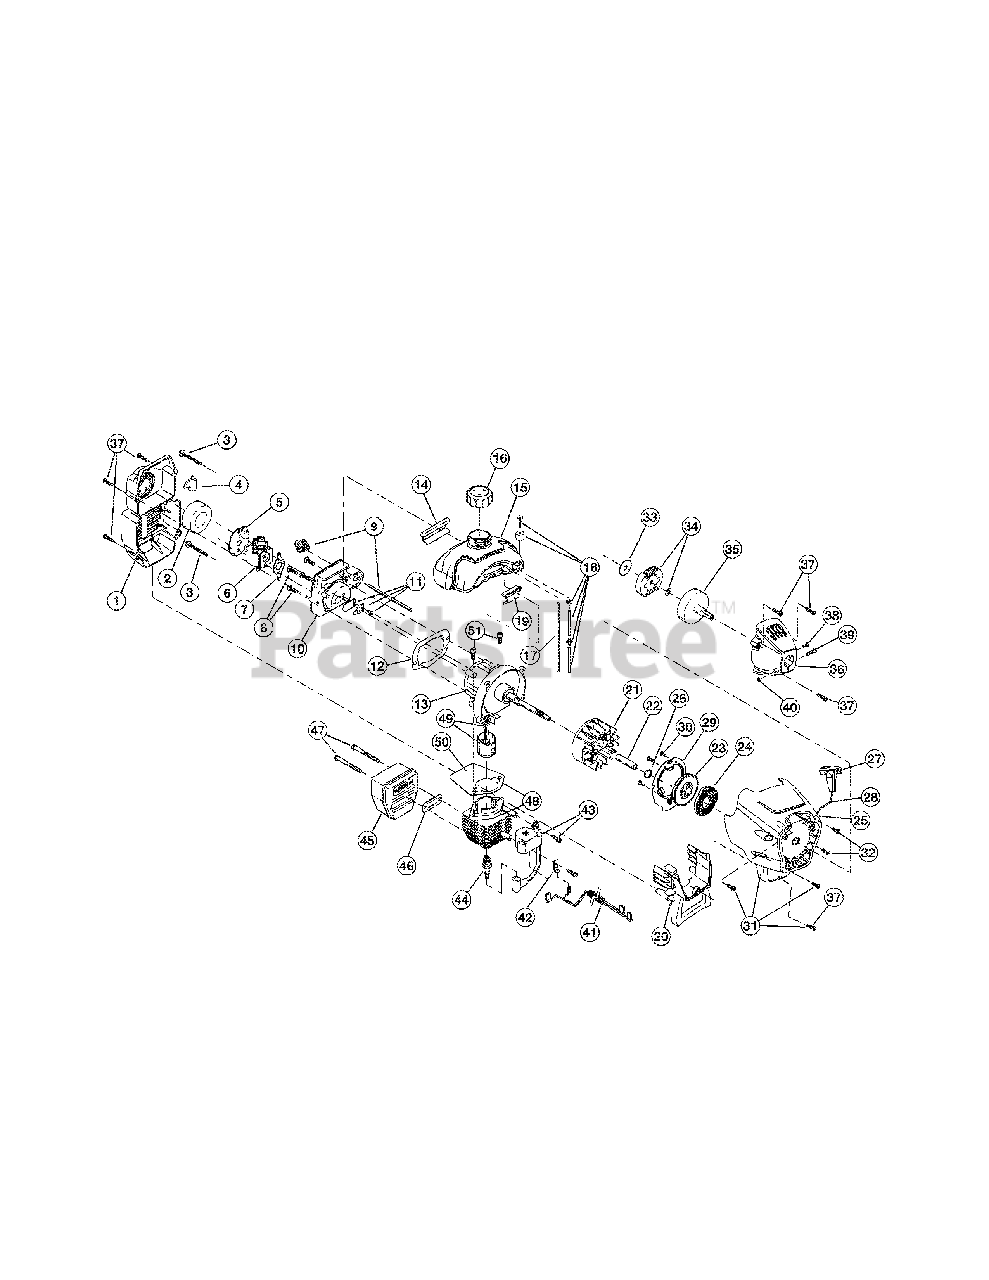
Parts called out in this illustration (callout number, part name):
1	Air Cleaner Assembly (includes 2 & 37)
2	Air Cleaner Filter
3	Carburetor Mounting Screw Assembly
4	Choke Extension
5	Choke Plate
6	Carburetor Assembly (includes 7 & 18)
7	Carburetor Gasket
8	Carb Mount Screw
9	Primer and Hose Assembly
10	Carb Mount Assembly (includes 8, 11 & 12)
11	Reed Assembly
12	Carburetor Mount Gasket
13	Crank Case Service Assembly (includes 8)
14	Rear Mounting Pad
15	Fuel Tank Assembly (includes 16-18)
16	Fuel Cap Assembly
17	Fuel Return Line
18	Fuel Line Assembly
19	Front Mounting Pad
20	Shroud Extension & Stand (includes 37)
21	Flywheel Assembly
23	Recoil Pulley Assembly (includes 26)
24	Recoil Spring
25	Rope Guide
26	Palnut
27	Pull Handle
29	Pressure Plate Assembly (includes 30)
30	Plate Screw
31	Starter Housing Assembly (includes 23-30, 32 & 37)
32	Housing Screw
33	Clutch Washer
34	Clutch Rotor Assembly
35	Clutch Drum Assembly
36	Clutch Cover Assembly (includes 37-40)
37	Cover Screw
38	Anti-Rotation Screw
39	Clamping Screw
40	Clamping Nut
41	Wire Leads and Sleeve
42	Ground Tab
43	Module Assembly (includes 42)
44	Spark Plug
45	Muffler Assembly (includes 46 & 47)
46	Exhaust Gasket
47	Muffler Mounting Bolt Assembly
48	Cylinder Assembly (includes 50 & 51)
49	Piston and Rod Assembly
50	Cylinder Gasket
51	Cylinder Bolt
